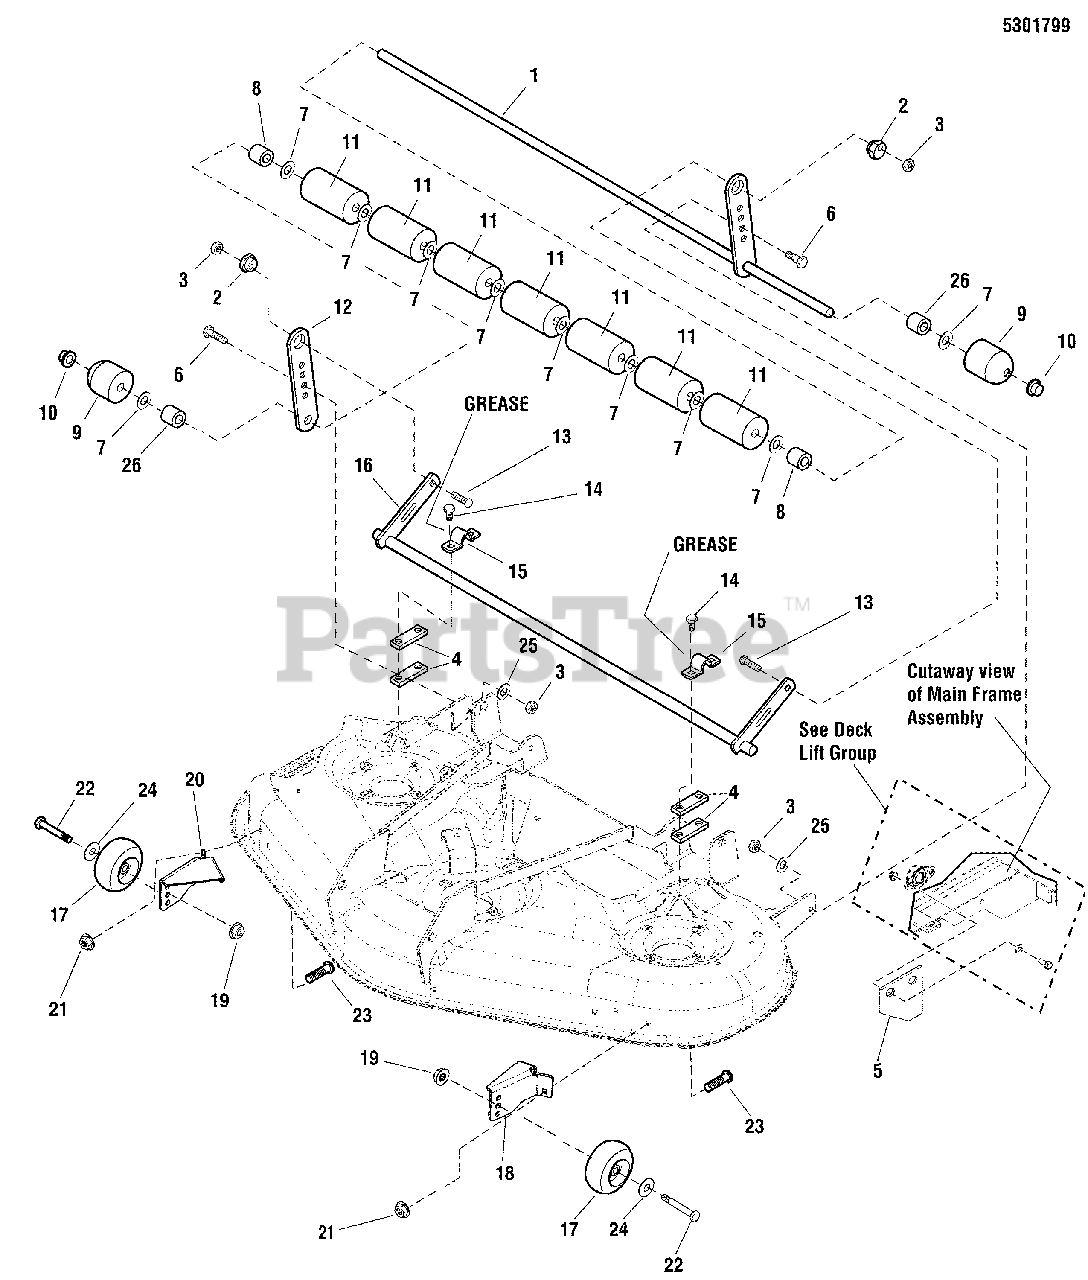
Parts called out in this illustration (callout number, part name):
1	WELD, SHAFT, ROLLER, 46 - ORG
2	NUT, Hex Adjusting, .99 DIA .687
3	NUT, 3/8-16 HEX NYLOCK FLANGE
4	PLATE, SPACER, ROLLER 46 - ORG
5	PLATE, DECK STOP
6	BOLT, 3/8-16 X 1-1/4, FLANGE
7	WASHER, 5/8
8	SPACER, .876 OD X .666 ID X 1.25 LG
9	ROLLER-0.650ID 2.50OD ROUNDED BLACK POLY
10	NUT-PUSH FOR .625 DIA STUD CAPPED BLK
11	ROLLER-0.652ID 2.50 OD 4.10LG BLACK POLY
12	BAR, ROLLER - ORANGE
13	RHSSNB, 3/8C X1-1/2 FLANGE GR5 YZ
14	SCREW-HEX WSHR HD TAPTT5/16-18X0.750BLK
15	STRAP, ROCKER SHAFT
16	WELD, SHAFT, ROLLER, 46 - ORG
17	WHEEL, GAUGE BLACK POLY 5" DIA
18	BRKT, GAUGE WHEEL, LH
19	NUT-HEX FLANGE 3/8-16 ESNA BLK
20	BRKT, GAUGE WHEEL, RH
21	NUT-HEX FLANGE 5/16-18, WHIZ LK SM, YZ
22	BOLT-SHLDR 3/8-16X3.41 .750 THRD YELLOW
23	BOLT-RD HD SH SQ NK 5/16-18X0.875 G5 BLK
24	WASHER-0.500(0.51IDX1.00ODX.10THK) BLK
25	WASHER, 3/8 GD9 FLAT
26	SPACER, .66 ID
